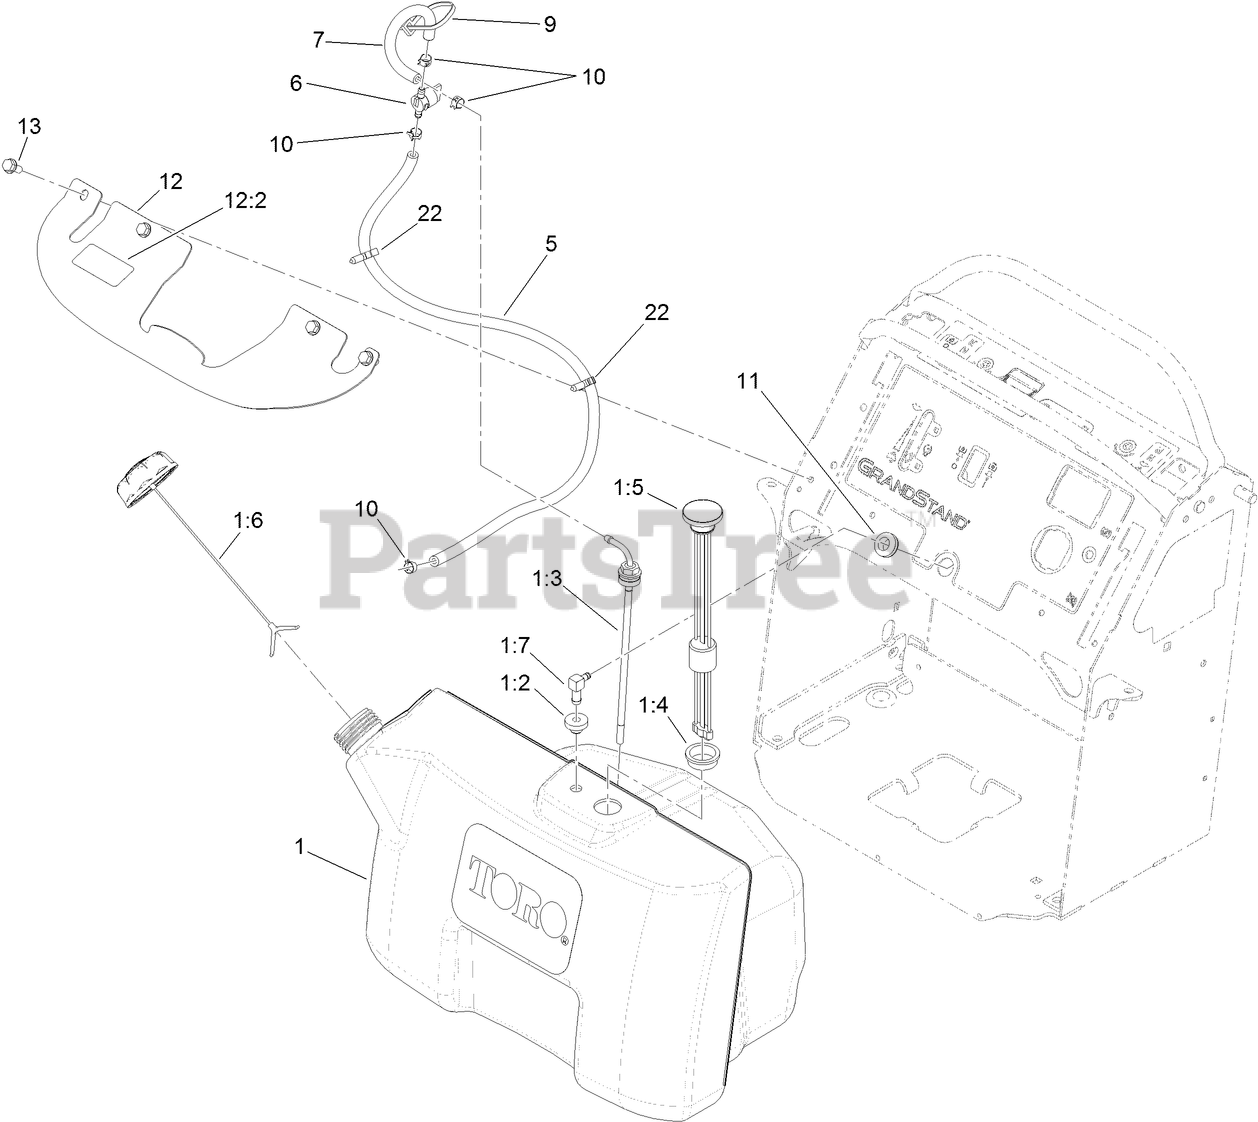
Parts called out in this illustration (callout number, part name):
1	TANK ASM
1:2	BUSHING
1:3	ELBOW-90 DEG
1:4	GROMMET
1:5	GUAGE-FUEL
1:6	CAP-FUEL, RATCHETING
1:7	FITTING-FUEL, BULKHEAD
5	HOSE-FUEL
6	VALVE-FUEL
7	HOSE-FUEL
9	TIE-CABLE
10	CLAMP-HOSE
11	GROMMET
12	BRACKET-TANK
12:2	DECAL-FILL, FUEL
13	SCREW-HWHTF
22	CLIP-HARNESS
